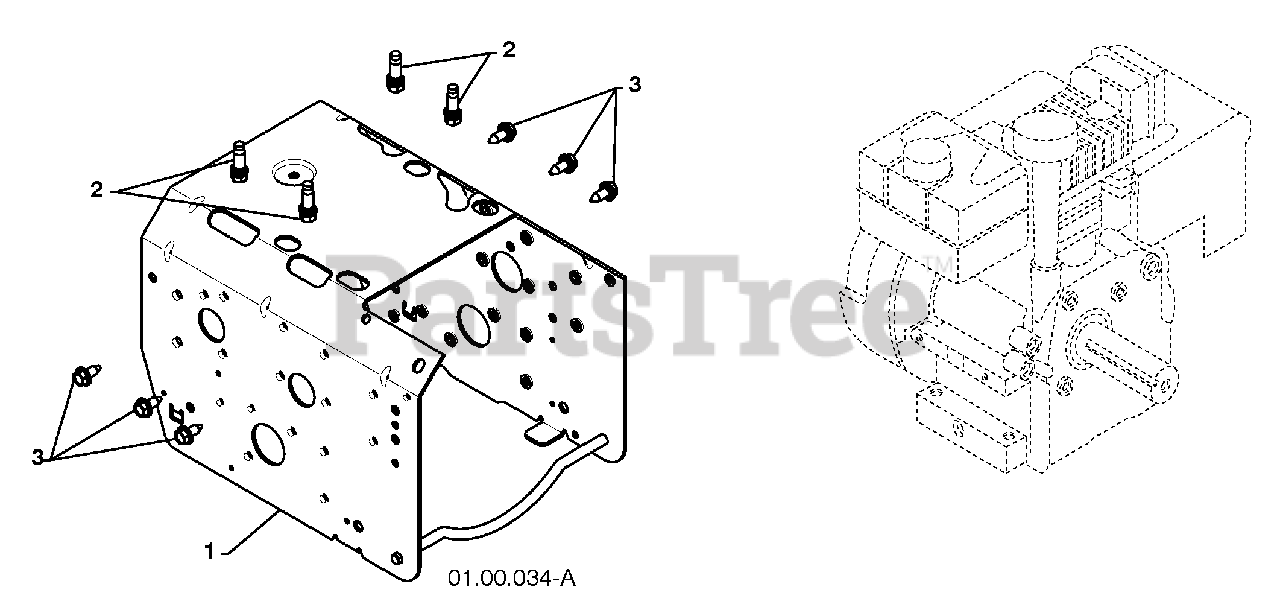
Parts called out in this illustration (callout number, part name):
1	FRAME
2	BOLT 3/8-16
3	SCREW 5/16-18 X .750
